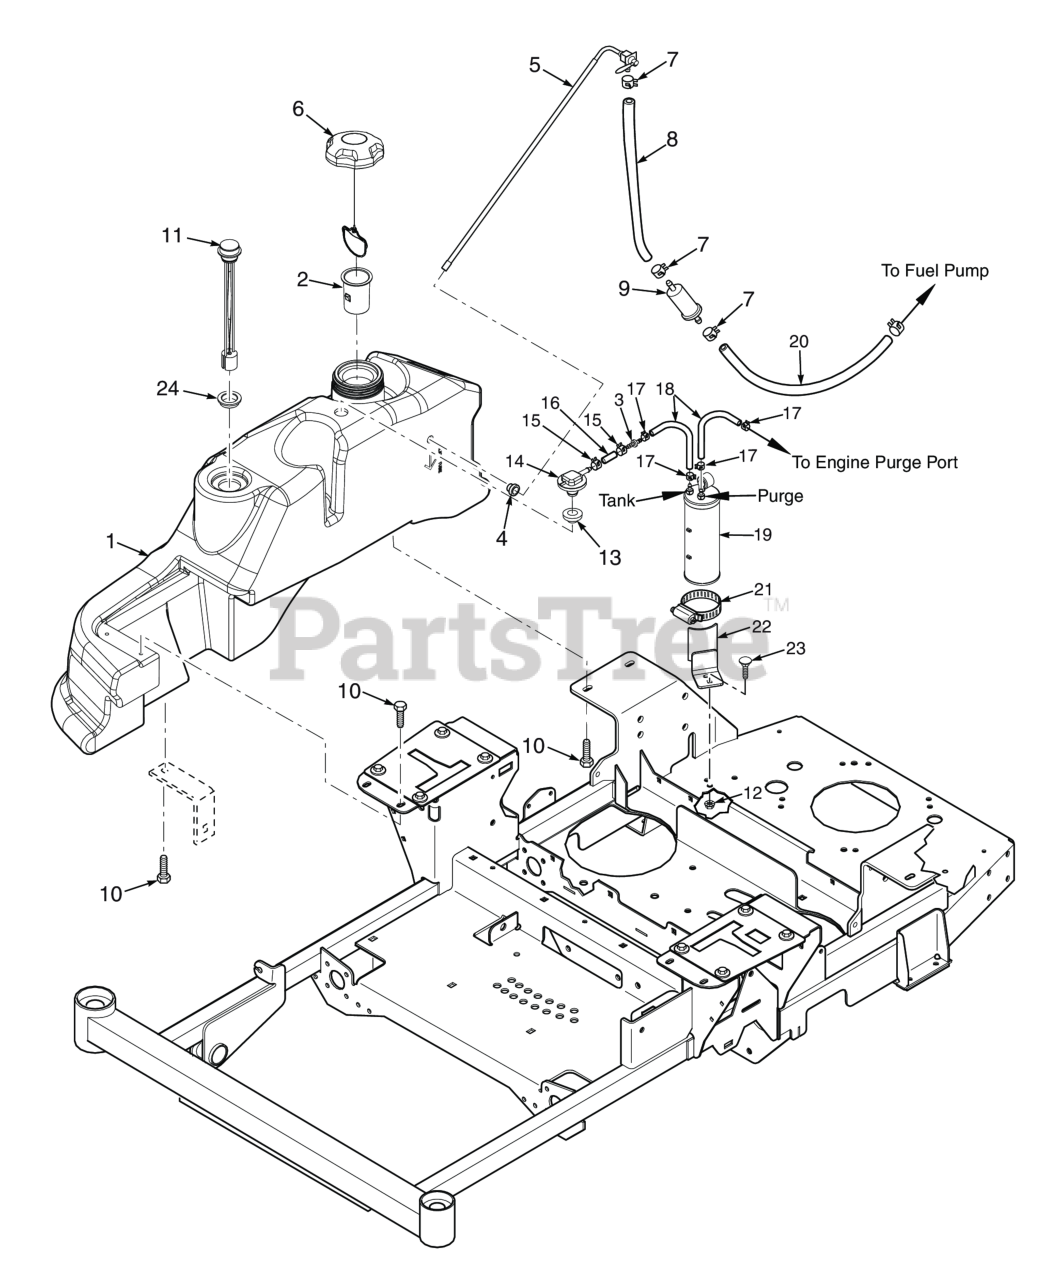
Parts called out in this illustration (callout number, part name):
1	Fuel Tank Assembly
2	Tube, Fuel Tank Insert - 4"
3	Mender, 1/4 x 3/16 w/0.02 Hole
4	Bushing, 0.56" Dia. Viton
5	Fuel Tube Assembly
6	Fuel Cap w/ Tether (E.P.A.)
7	Clamp, Fuel Hose 1/4" Hose I.D.
8	Fuel Hose, 1/4" I.D. Non-Perm (791DFI Fuel Return) - Order by Inch
9	Fuel Filter
10	Capscrew, 5/16-18 x .75 Serrated Flange Hex Head
11	Fuel Gauge Assembly
12	Nut, Serrated Flange 5/16-18 (Right Front Engine Mounting, Briggs and Kohler Only)
13	Grommet, Viton,
14	Remote Vent, No Valve
15	CLAMP, FUEL HOSE(KAWASAKI ONLY)
16	Hose, 1/4" Vapor Recovery (order by inch)
17	Clamp, Vapor Recovery Hose 3/16"
18	Hose, Vapor Recovery 3/16" (order by inch)
19	Carbon Canister - SVR-52V / SVR-61V
20	Fuel Hose
21	Clamp, 3-1/2" Max. Dia.
22	Bracket Weldment - SPZ61H
23	Bolt, 5/16-18 x .75 RHSN Carriage
24	Grommet, Fuel Gauge
